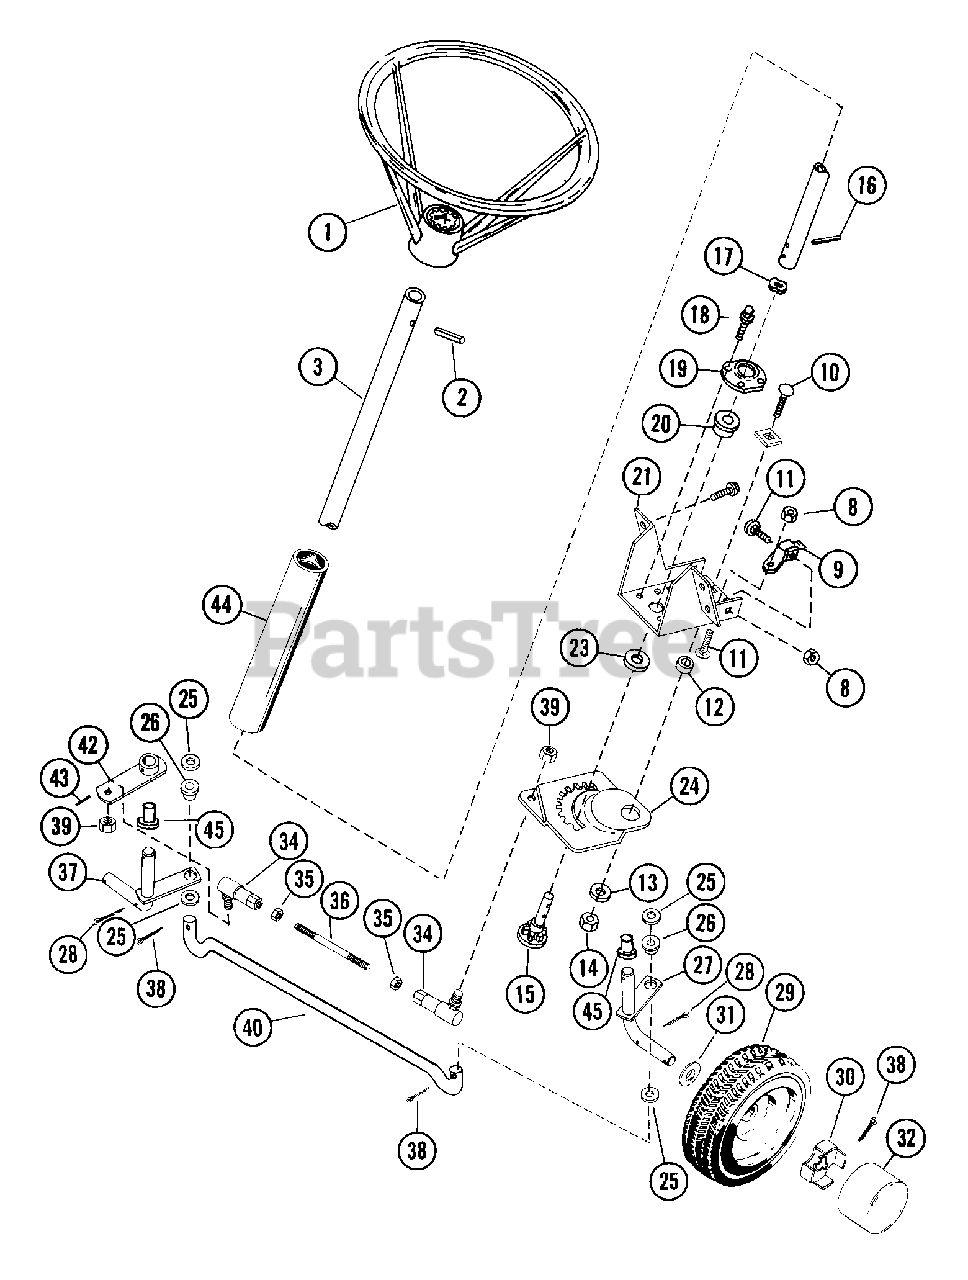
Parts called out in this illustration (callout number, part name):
1	STEERING WHEEL
2	PIN-ROLL .250X1.75
3	STEERING SHAFT
8	NUT-LK-CTR .250-20 PL
9	ADJUSTMENT BRACKET
10	BLT-RDHDSQSHNK .38-16X1.00 PL
11	BLT-RDHDSQNK .25-20X.62 PL
12	SPACER .380X.750X.236
13	WSHR-FL-STL .390X1.500X.125
14	NUT-LK-JAM-CTR .375-16 PL
15	PINION
16	PIN-ROLL .188X1.00
17	WAVE WASHER .531X.781X.125FH
18	SCR-TAP 10-24X.25 CRSLPH PL 1A
19	RETAINING PLATE
20	BSHG-FLG .625X1.156X.375 SI
21	STEERING BRACKET
23	WSHR-FL-STL .630X1.250X.062 PL
24	STEERING GEAR
25	WSHR-FL-STL .505X.875X.024 PL
26	BSHG-FLG.500X.625X.312X.750NY
27	L H WHEEL SPINDLE
28	PIN-COTR .12 X 1.25 PL
29	FRONT WHEEL ASSEMBLY
29	TIRE 4.10/3.50-4
29	WHL
29	ZERK FITTING
29	BSHG-FLG .750X1.380X.750X1.557
30	SPINDLE CUP
31	SPINDLE WASHER
32	HUB CAP
34	BALL JOINT
35	NUT .375-24 PL
36	STEERING LINK
37	SPINDLE
38	PIN-COTR .12X1.0 PL
39	NUT-LK .375-24 PL
40	TIE ROD
43	PIN-GRV .250X1.25 TP A
45	FLANGE BUSHING
